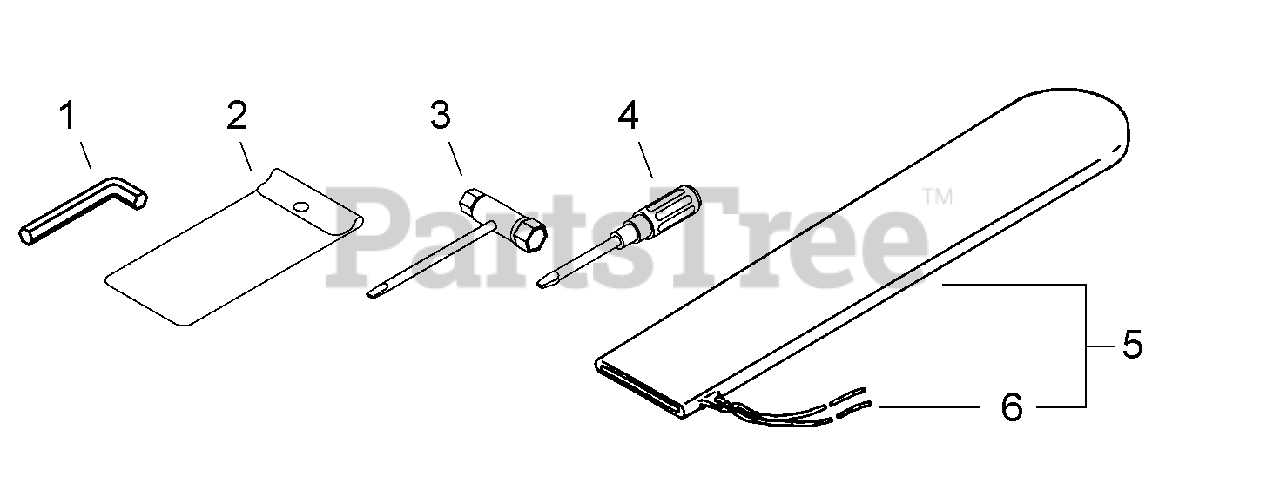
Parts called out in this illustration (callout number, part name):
1	WRENCH, ALLEN 4 MM
2	BAG, TOOL
3	T-WRENCH 13×19 L= 180
4	SCREWDRIVER, PHILLIPS
5	SCABBARD
6	ROPE 5×900
